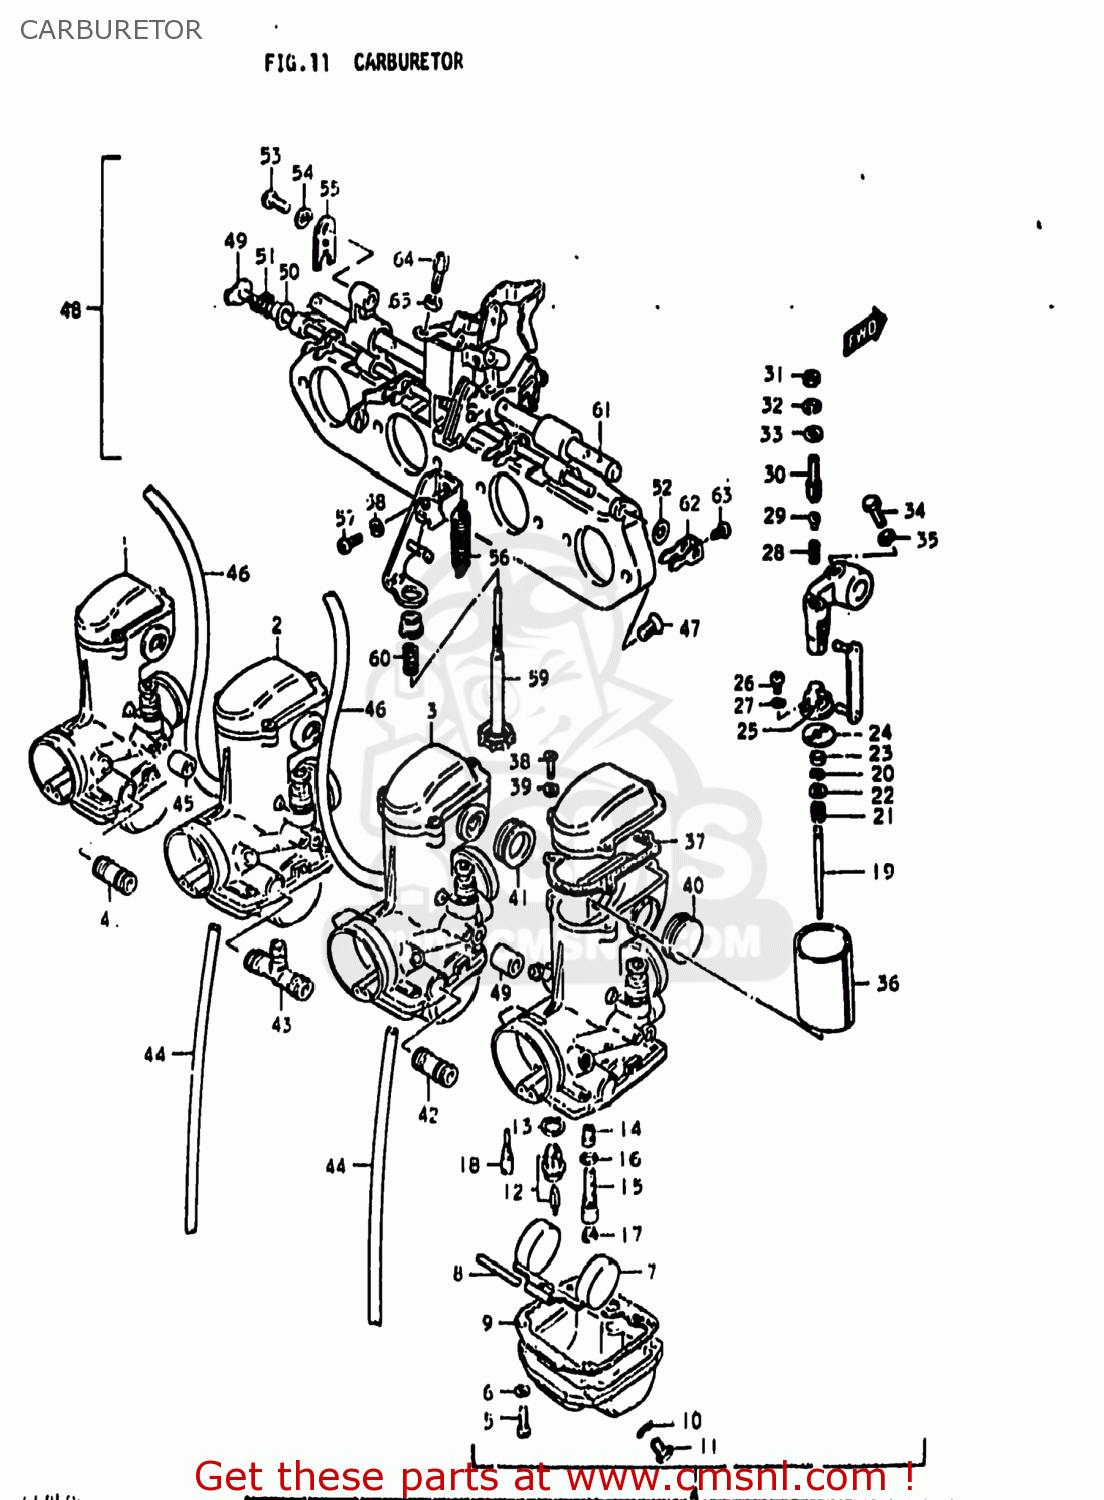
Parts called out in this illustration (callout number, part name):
1	CARBURETOR ASSEMBLY
2	CARBURETOR ASSEMBLY
3	CARBURETOR ASSEMBLY
4	CARBURETOR ASSEMBLY
5	SCREW
6	LOCK WASHER
7	FLOAT
8	PIN,FLOAT
9	GASKET,FLOAT CHAMBER (NAS)
10	O RING
11	SCREW
12	VALVE ASSEMBLY,NEEDLE
13	GASKET,VALVE SEAT (NAS)
14	JET,NEEDLE
15	PIPE,BLEEDER
16	O RING
17	JET,MAIN(102.5)
18	JET,PILOT
19	NEEDLE,JET
20	CLIP
21	SPRING
22	WASHER,JET NEEDLE
23	RING
24	PLATE,THROTTLE VALVE
25	CONNECTOR
26	SCREW
27	LOCK WASHER
28	SPRING
29	PIN,CARBURETOR
30	SCREW
31	NUT
32	LOCK WASHER
33	WASHER
34	BOLT
35	LOCK WASHER
36	VALVE,THROTTLE
37	GASKET (NAS)
38	SCREW
39	LOCK WASHER
40	PIPE,DELIVERY
41	SEAL
42	NIPPLE
43	NIPPLE
44	HOSE
45	HOSE
46	HOSE 4.5X8X390
47	SCREW
48	CARBURETOR ASSEMBLY
49	SHAFT,STARTER
50	WASHER
51	SPRING
52	WASHER,STARTER SHAFT
53	SCREW
54	LOCK WASHER
55	GASKET
56	SPRING,THROTTLE RETURN
57	SCREW
58	LOCK WASHER
59	ADJUSTER
60	SPRING,THROTTLE SCREW
61	SHAFT ASSEMBLY
62	LEVER,STARTER
63	SCREW
64	ADJUSTER,CABLE
65	NUT
